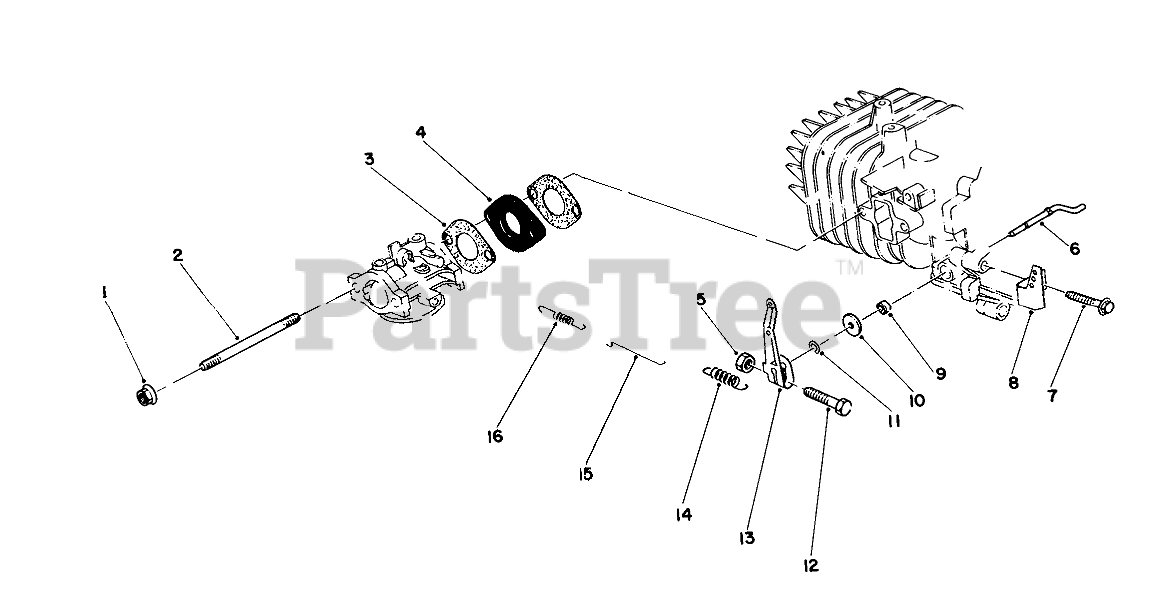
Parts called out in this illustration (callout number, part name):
1	M6 X 1 LOCKNUT
2	Stud-Bolt-Carburetor
3	GASKET-CARB
4	CARB. INSULATOR
6	Shaft-Govemor
8	Bracket-Governor Spring
9	SEAL-OIL
10	WASHER
11	E-RING
13	Lever-Throttle Control
14	GOVERNOR SPRING
15	ROD-CARBURETOR
16	SPRING
